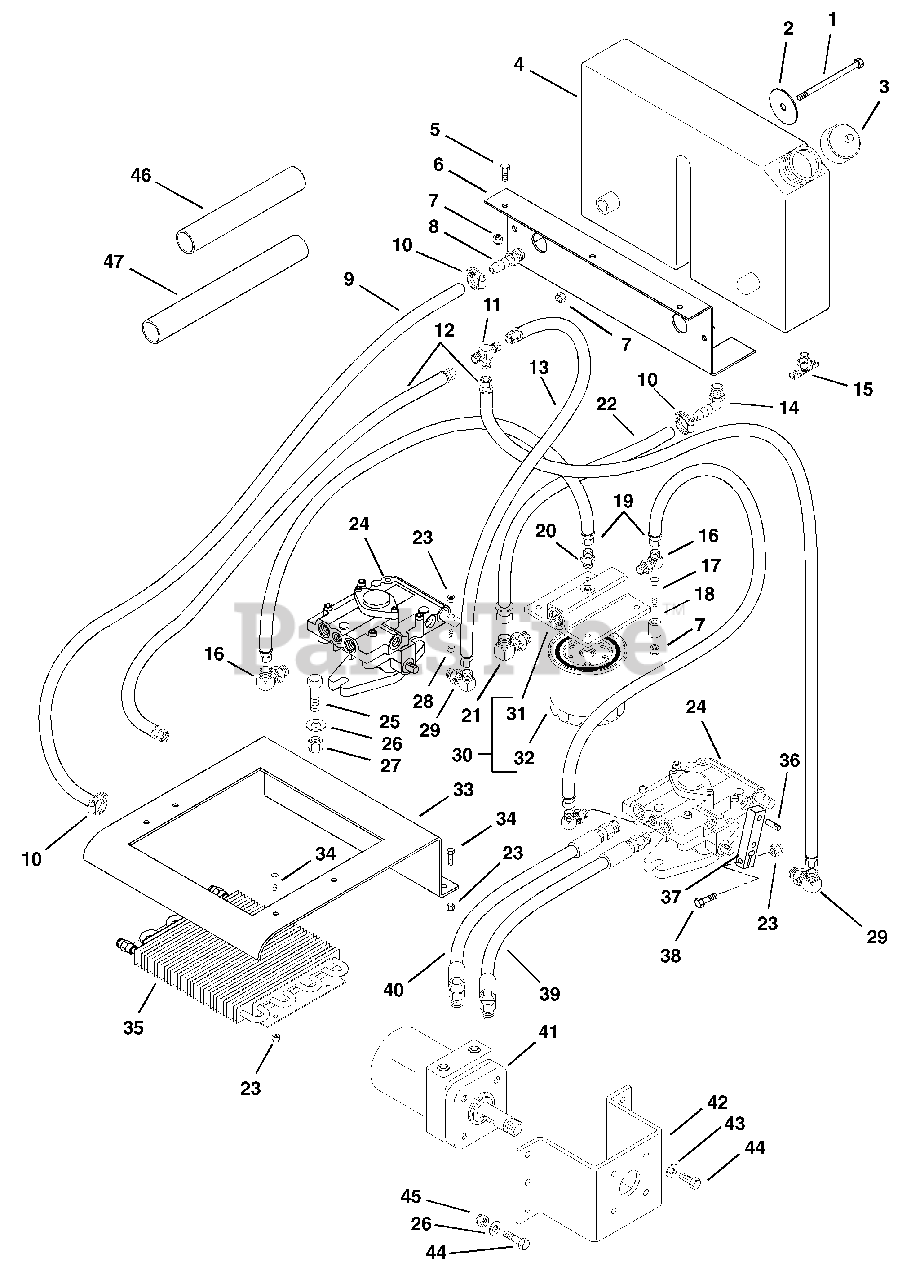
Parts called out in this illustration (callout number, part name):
1	@BLT-HEX .31-18X3.50 GR5 YWZC
2	WSHR,FL .344X3.0X .060
3	CAP,TANK
4	TANK,HYDRAULIC
5	@BLT-HEX .31-18X.75 GR5 YWZC
6	BRKT,HYD TANK MTG
7	@NUT-LK-CTR .31-18 YWZC
8	ADAPTOR, MALE 3/8X1/2
9	HOSE, HYDRAULIC
10	CLAMP,.88 DIA. HOSE
11	ADPT-TEE .56-18
12	HOSE,HYD VALVE TO TANK
13	HOSE,PUMP TO TEE
14	FTG-ELBOW .50X.50
15	COCK-DRAIN .38X.69X1.25
16	ADPT 2503-4-4
17	@BLT-HEX .31-18X2.00 GR5 YWZC
18	BUSH.,SPLIT .328X.462X.75 ST
19	HOSE,OIL FILTER TO PUMP
20	ADPT 0503-4-4
21	ADPTR-HYD EL 3/4 "O" TO 3/4
22	HOSE,TANK TO OIL FILTER
23	@NUT-LK-CTR .25-20 YWZC
24	PUMP, BDP-10L
25	@BLT-HEX .38-16X1.00 GR5 YWZC
26	WSHR-FL-STL.406X.812X.065 YWZ
27	@NUT-LK-CTR .38-16 YWZC
28	@BLT-HEX .25-20X2.00 GR5 YWZC
29	FTG, 90 9/16 MOR X 9/16 MJIC
30	ASM,SPIN-ON LUBE
31	ASM,HEAD
32	ELEMENT
33	OIL COOLER BRACKET
34	@BLT-HEX .25-20X.75 GR5 YWZC
35	COOLER,OIL
36	PIN-DWL .312X1.25
37	ARM, PUMP ACTUATING
38	@BLT-HEX .25-20X1.25 GR5 YWZC
39	KIT, PRO300 WHEEL MTR HOSE-SH
40	KIT, PRO300 WHEEL MTR HOSE -LG
41	MOTOR, HYD WHL (MF160933AAFB)
42	BRKT,WHEEL MOTOR
43	@WSHR-LK .38X.094 REG YWZC
44	@BLT-HEX .38-16X1.25 GR5 YWZC
45	@NUT-LK-CTR .38-16 YWZC
46	SLEEVE 12"
47	SLEEVE 18"
